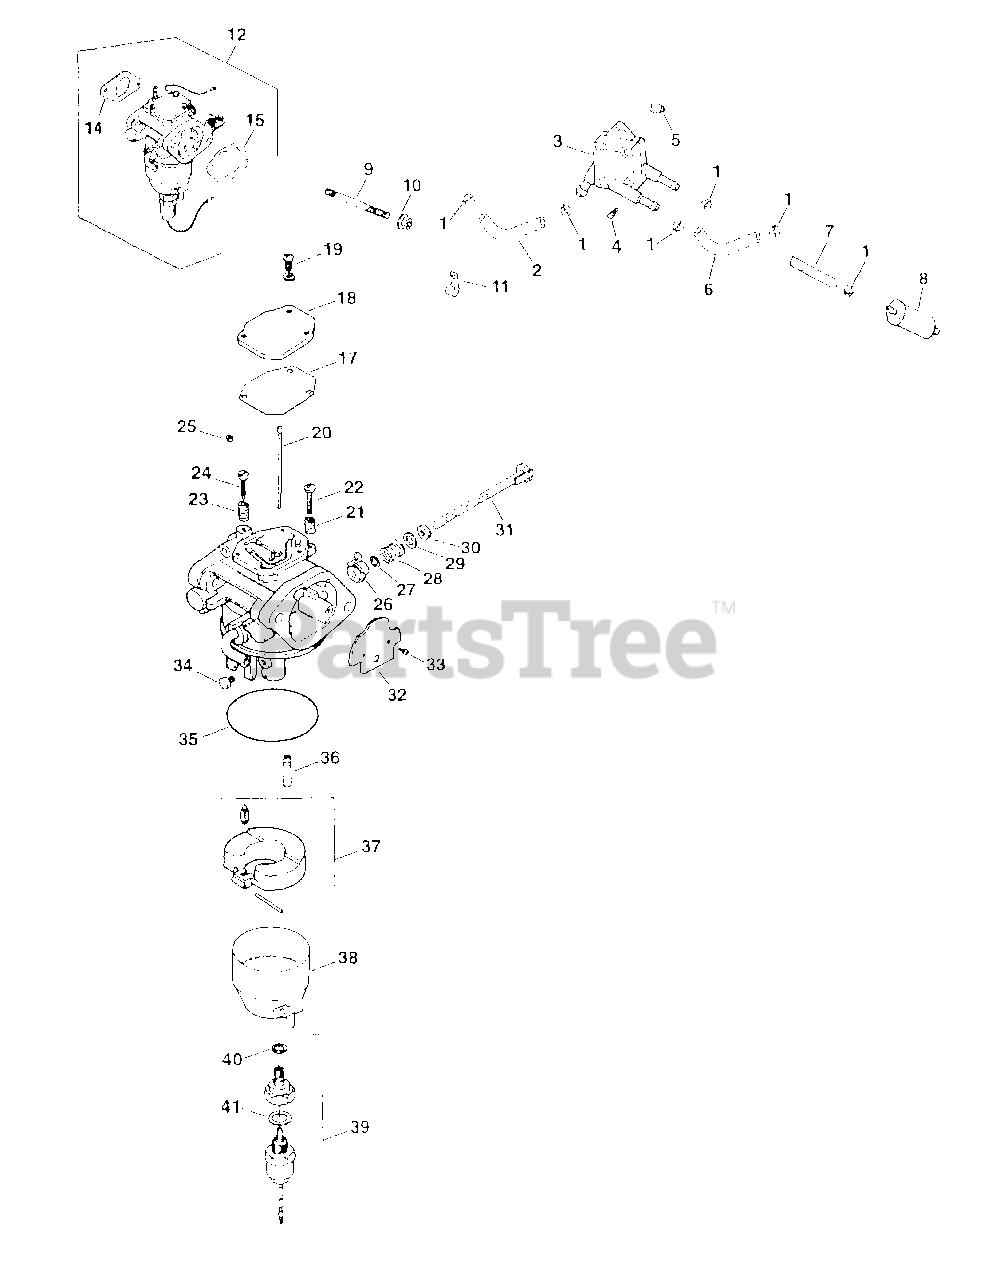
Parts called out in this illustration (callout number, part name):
1	Clamp, Hose
2	Line, Fuel 11-1/2"
3	Pump, Fuel-Pulse
4	Screw, Hex Cap
6	Line, Fuel 10-5/8"
7	Line, Fuel 3-1/2"
8	Filter, Fuel
9	Stud
12	Kit, Carburetor w/Gaskets
14	Gasket, Carburetor
15	Gasket, Air Cleaner Base
17	Gasket, Passage Cover
18	Cover, Passage
19	Screw, Sems Pan Head
20	Jet, Slow
21	Spring, Idle Adjusting Screw
22	Screw, Idle Adjusting
23	Spring, Throttle Adjusting Screw
24	Screw, Throttle Adjusting
25	Jet, Air Bleed
26	Lever, Choke
27	Ring, Choke Lever
28	Spring, Choke Return
29	Collar, Choke
30	Washer, Felt
31	Shaft, Choke
32	Plate, Choke
33	Screw, Sems Pan Head
34	Jet, Main
35	Gasket, Float Chamber
36	Nozzle, Main
37	Kit, Float
38	Chamber, Float
39	Kit, Solenoid Valve
40	Gasket, Chamber Screw
41	Gasket, Solenoid
